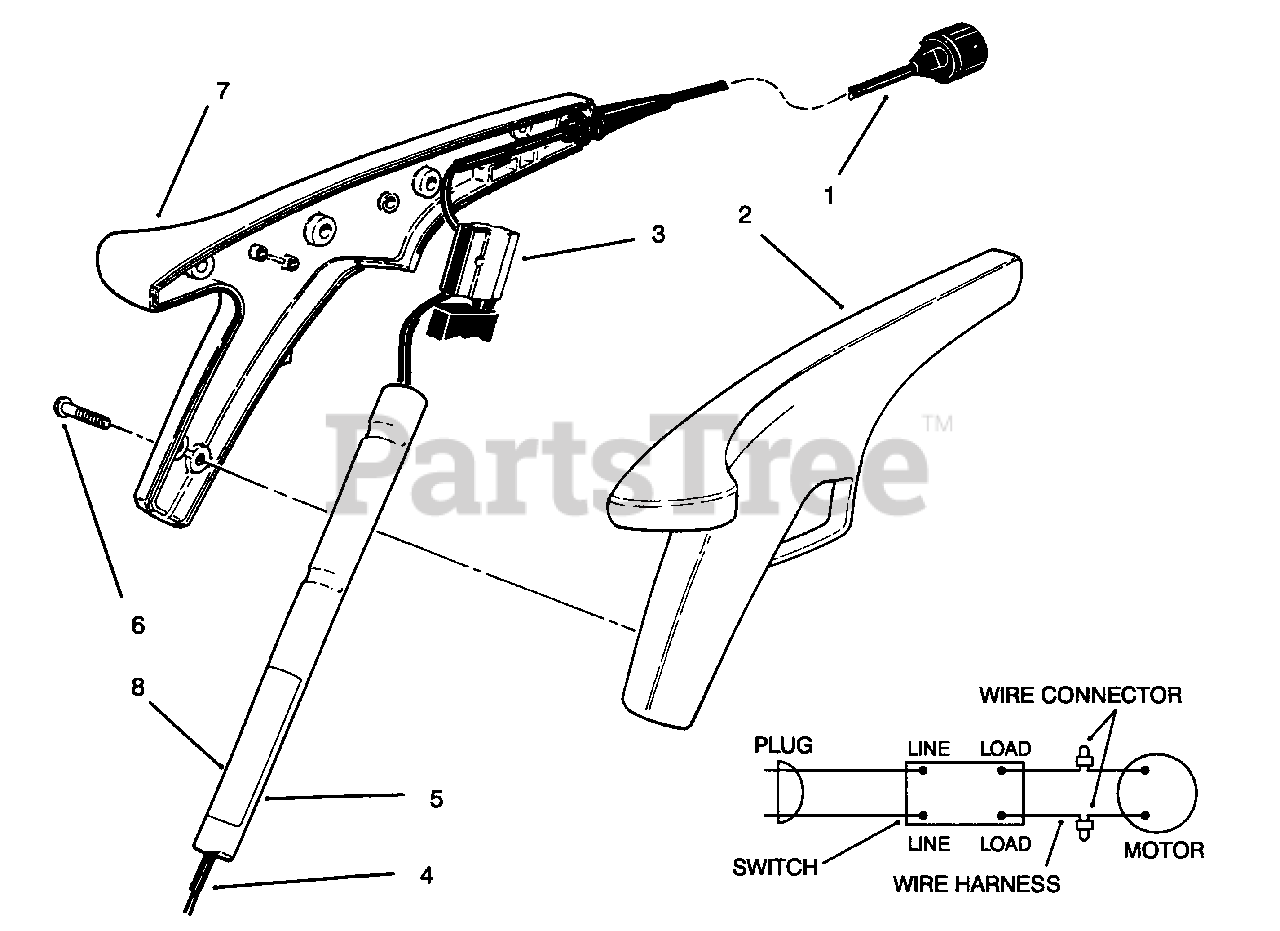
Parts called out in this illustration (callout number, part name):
1	Cord-Power
2	Grip-L.H.
4	Harness-Wiring
5	Tube Assy. (Incl. Ref.# 8) Screw
6	Screw
7	Grip-R.H.
8	Decal-Safety
